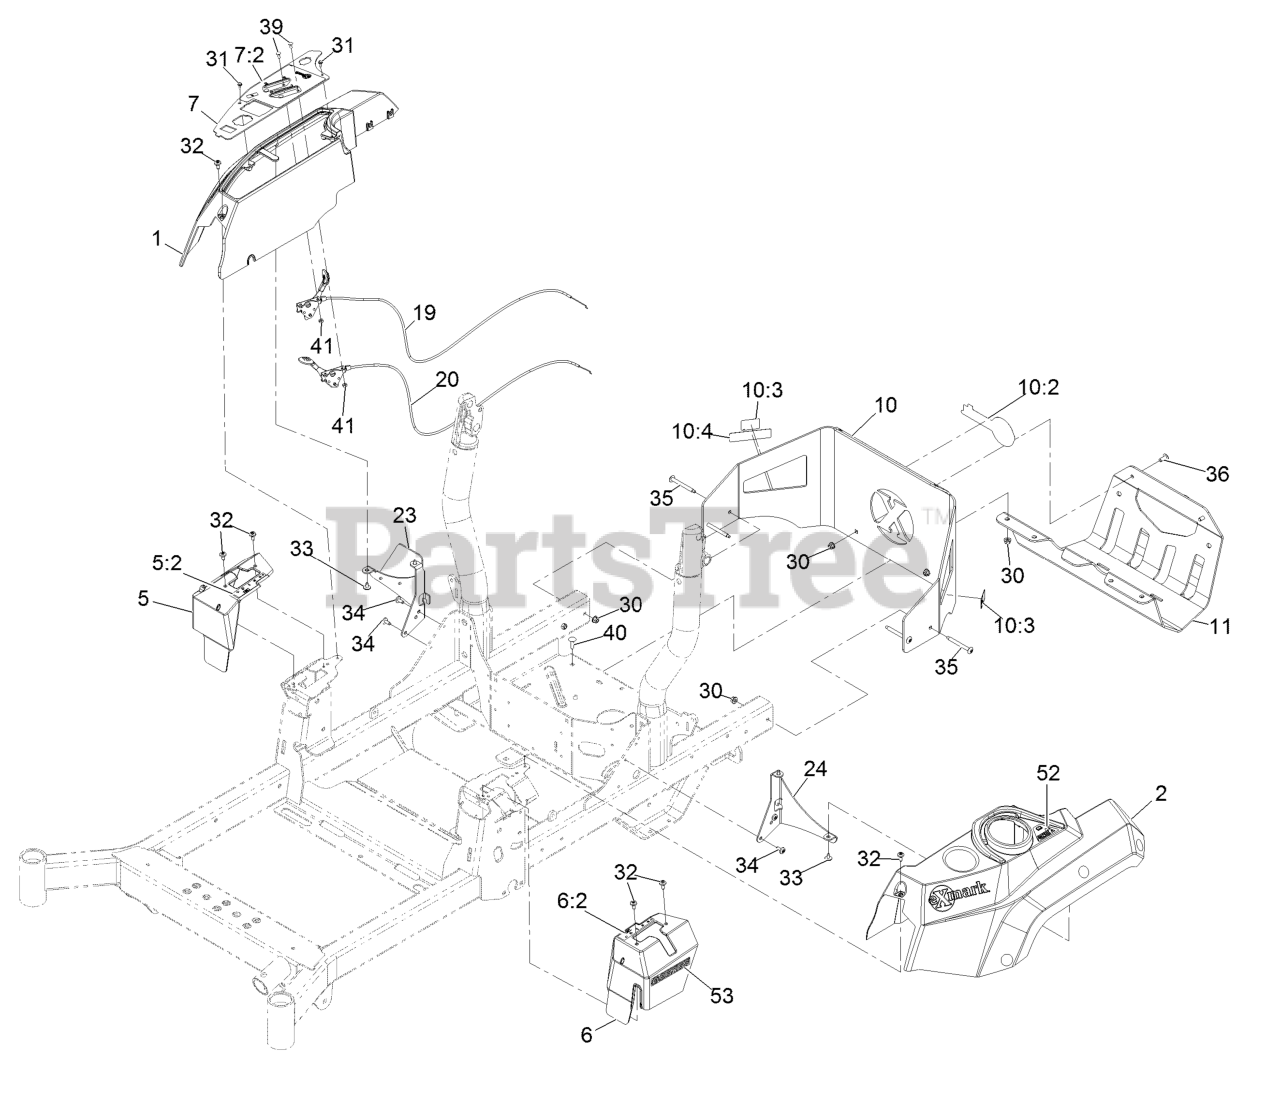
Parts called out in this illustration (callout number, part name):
1	Console, RH
2	Console, LH
5	Cover-Control, Motion (RH)
5:2	Decal-Control, Motion (RH)
6	Cover-Control, Motion (LH)
6:2	Decal-Control, Motion (LH)
7	Ctrl Panel ASM W/Decal
7:2	Decal-Control Panel
10	Rear Guard ASM
10:2	Decal-Exmark Logo
10:3	Decal-Warning
10:4	Decal-Arrester, Spark
11	Guard-Muffler
19	Cable-Control, Choke
20	Cable-Control, Throttle
23	Support-Console, RH
24	Bracket-Console, LH
30	Nut-Nyloc 5/16-18 Flg
31	Screw-HWH #10-14 X 1/2
32	Screw-1/4-20 X 1/2 Tf Torx Plus
33	Screw-HWH #10-14 X 1/2 Torx
34	Screw-1/4-20 X .65 Torx Plus
35	Screw-Truss HD 5/16-18 X 2 3/4 Torx Plus
36	Screw-Truss HD 5/16-18 X 3/4 Torx Plus
39	Bolt-Carriage #10-24 X 1/2
40	Bolt-Carriage 5/16-18 X 1 Sp
41	Nut-Nyloc #10-24
52	Decal-Fill, Fuel
53	Decal-E-Series
